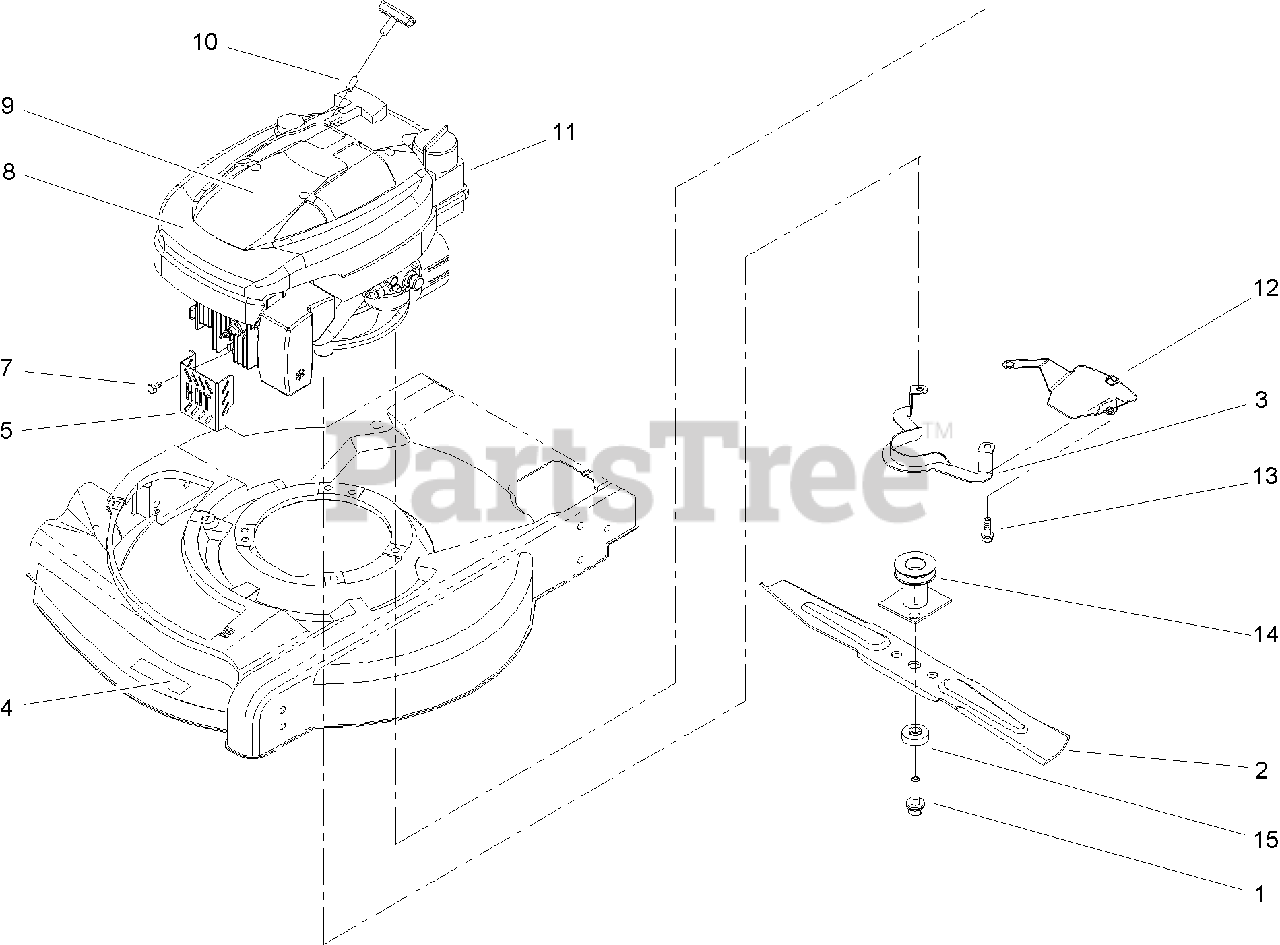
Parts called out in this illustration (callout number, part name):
1	BOLT-BLADE
3	GUIDE-BELT
4	DECAL-DECK
5	GUARD-MUFFLER
7	SCREW-HWH
8	APPLIQUE
9	DECAL-RECOIL
10	STOP-ROPE
12	SHIELD-GRASS
13	SCREW-TAPTITE
14	DRIVER-BLADE
